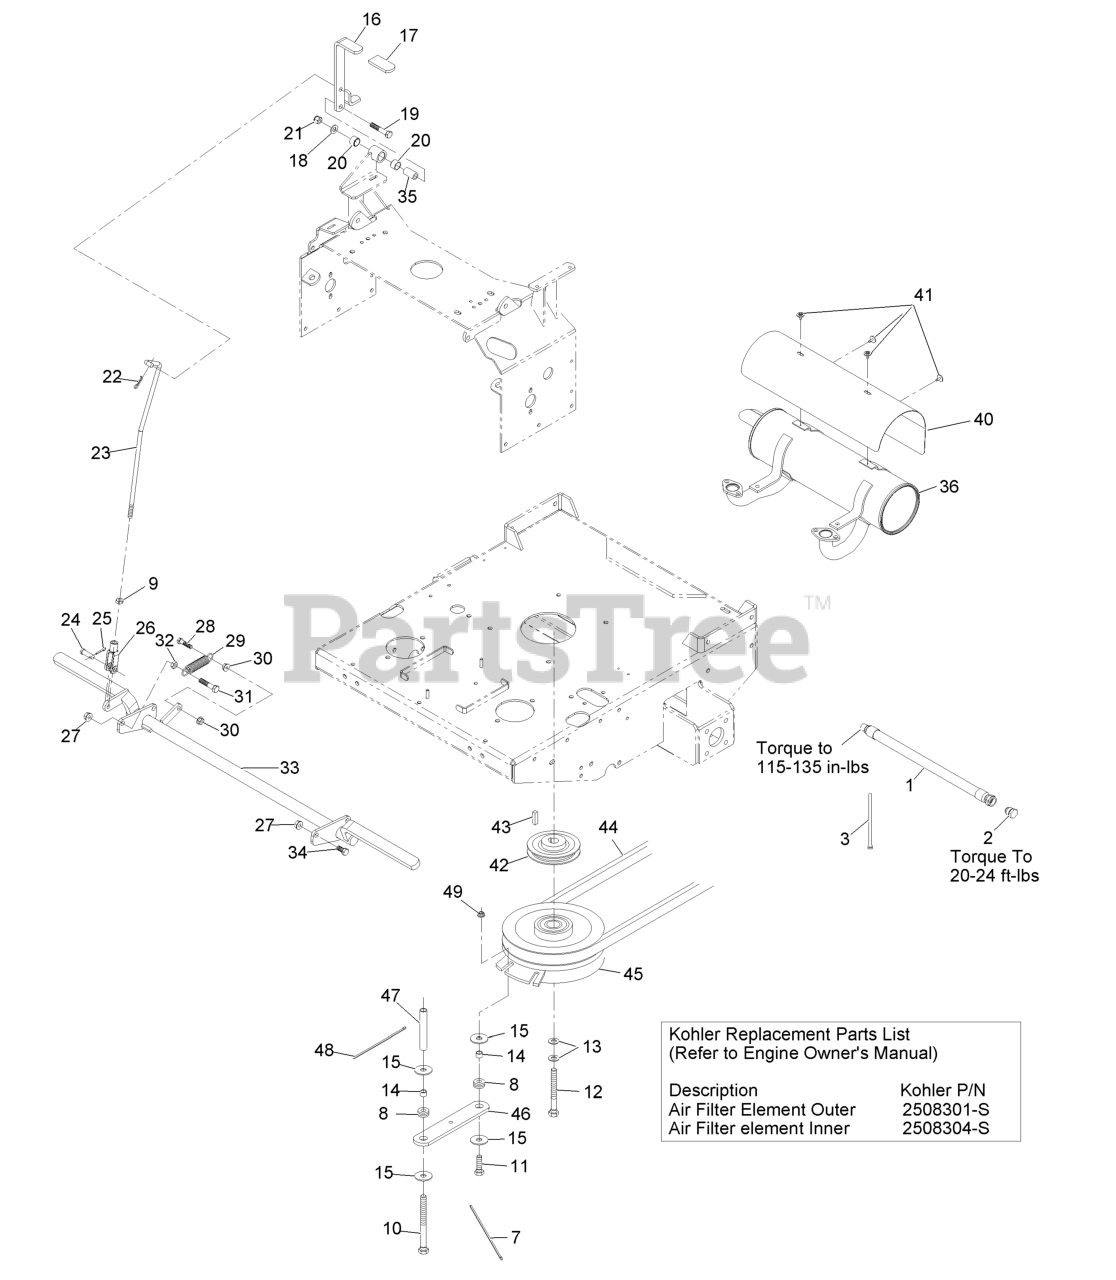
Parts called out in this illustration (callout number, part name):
3	TIE-PLASTIC
7	TIE-PLASTIC
8	GROMMET
9	NUT-HJ
10	SCREW-HH
11	SCREW-HH
12	SCREW-HH
13	WASHER-SPRING
16	LEVER,PRK BRK W/DECALS
17	GRIP-LEVER
18	WASHER-FLAT
19	SCREW-HH
20	SLEEVE-BUSHING
21	NUT-LOCK, NI
22	PIN-COTTER
23	LINKAGE, PARK BRAKE
24	PIN-CLEVIS
25	PIN-COTTER
26	YOKE-LINKAGE, BRAKE
27	NUT-HHF, WHIZ
28	SCREW-HH, SPECIAL
29	SPRING-IDLER
31	SCREW-HH
32	NUT-JAM
34	SCREW-HH
35	BUSHING-PIVOT
36	MUFFLER, KOHLER 20HP
40	SHIELD, MUFFLER 20HP
41	SCREW-HH, THREAD FORMING
42	PULLEY
44	BELT,B 83.65
44	BELT,DECK DRIVE
45	CLUTCH ASM
46	STRAP-CLUTCH, BRAKE
47	SPACER,SHIELD
48	TIE-CABLE
